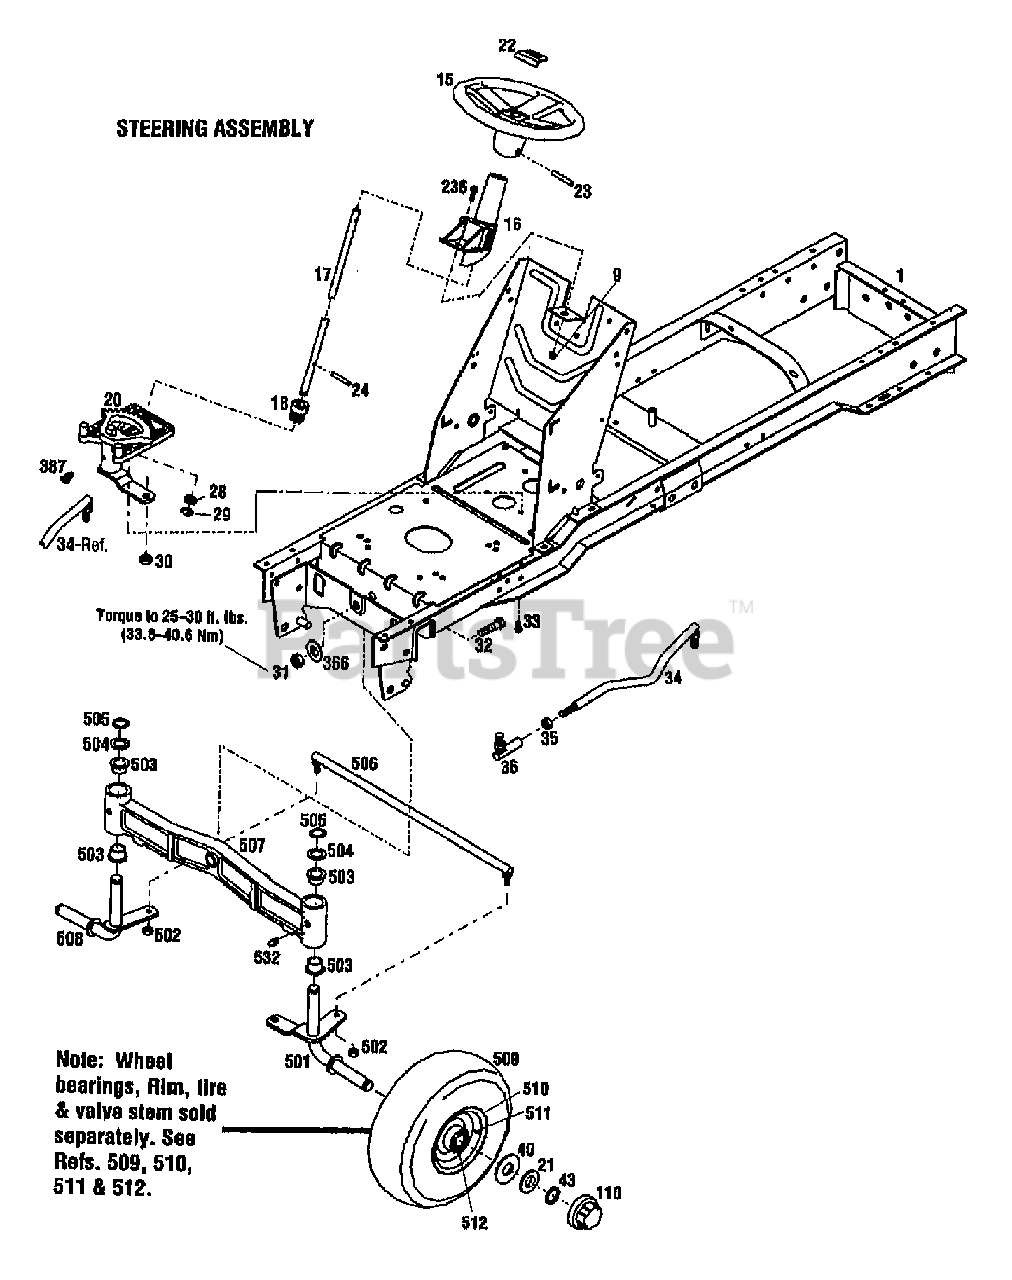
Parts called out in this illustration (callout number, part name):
9	NUT-HFLK 5/16-18 ZP
15	WHEEL-STEERING
16	SUPPORT-STEERING SHAFT
17	SHAFT-STEERING
18	GEAR-PINION
20	ASSM-STEERING GEAR
21	WASHER-THRUST
22	CAP-STEERING
23	PIN-ROLL .25X2.25
24	PIN-ROLL 1/4 X 1-1/4
28	WASHER-1.0X.64X.09
29	RING-RETAINING
30	NUT-HEX/JAM 1/2-20
31	NUT-H/LK 5/8-11
32	SCR-HH
33	SCR-HFLK 5/16-18X.75
34	LINK-DRAG
35	NUT-JAM
36	JOINT-BALL
40	WASHER-SPECIAL .75X2.5
43	RING-HEAVY EXT HD 1.0 ID
110	CAP-HUB
236	SCR-HFLK 5/16-18X.75 ZP
366	WASHER-1.75X.687X.134 ZP
387	FITTING-GREASE 90 DEGREE
501	SPINDLE-WHEEL LH
502	NUT-LOCK
503	BEARING-FLANGE
504	WASHER-THRUST
505	RING-HEAVY EXT HD 1.0 ID
506	KIT-TIE ROD W/HDW
507	AXLE-FRONT
508	SPINDLE-WHEEL RH
510	RIM-WHEEL
511	STEM-VALVE
512	BEARING-BALL
532	FITTING-GREASE 1/4-28X2.00
